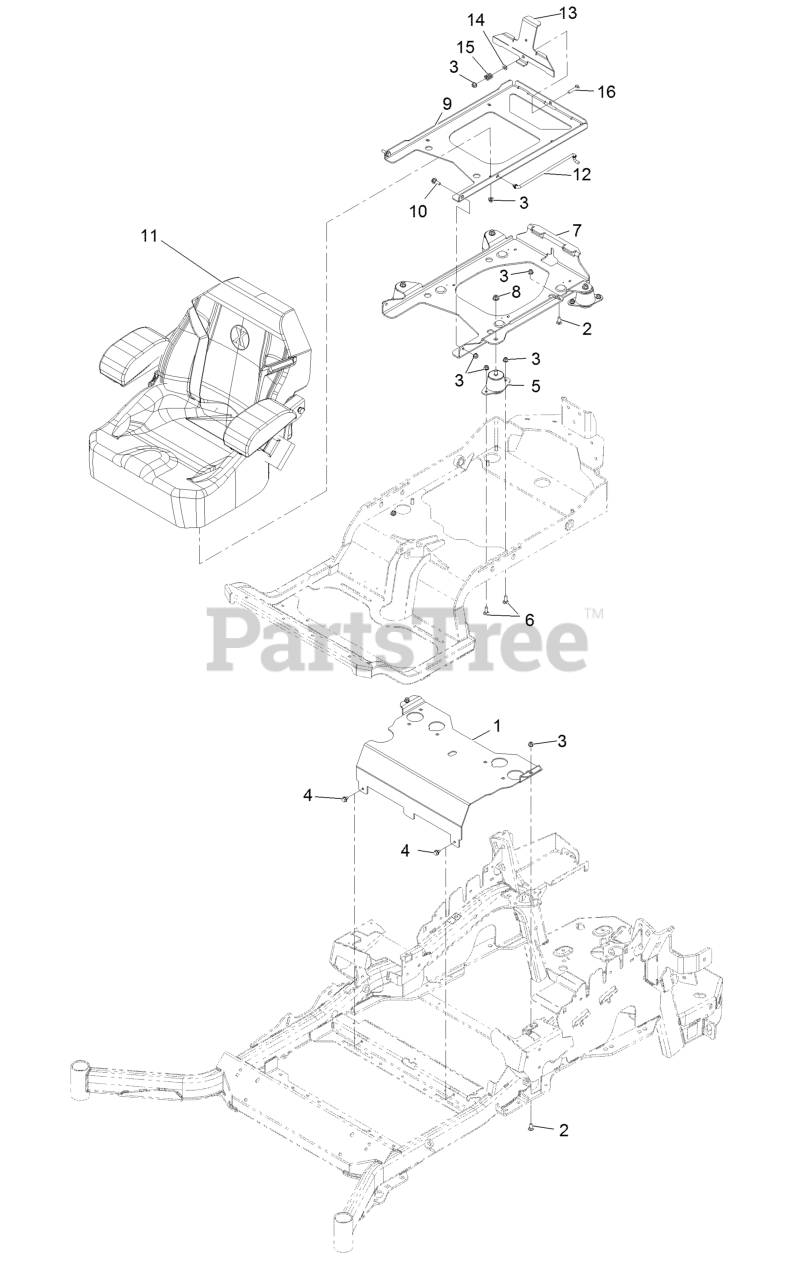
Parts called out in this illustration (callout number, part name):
1	Panel-Front, Seat Mount
2	Bolt-Carriage 5/16-18 X 3/4 Short Neck
3	Nut-Nyloc 5/16-18 Flg
4	Screw-HWH 5/16 X 1/2 Tf
5	Isolator-Seat
6	Bolt-Carriage 5/16-18 X 7/8
7	Plate-Support, ISO Seat
8	Nut-Nyloc 3/8-16 Flg
9	Plate-Frame, Seat
10	Screw-Shoulder
11	Seat-Exmark Standard
12	Rod-Prop
13	Plate-Latch,Seat
14	Washer-5/16 SAE
15	Spring-Compression
16	Bolt-Carriage 5/16-18 X 1 1/2
